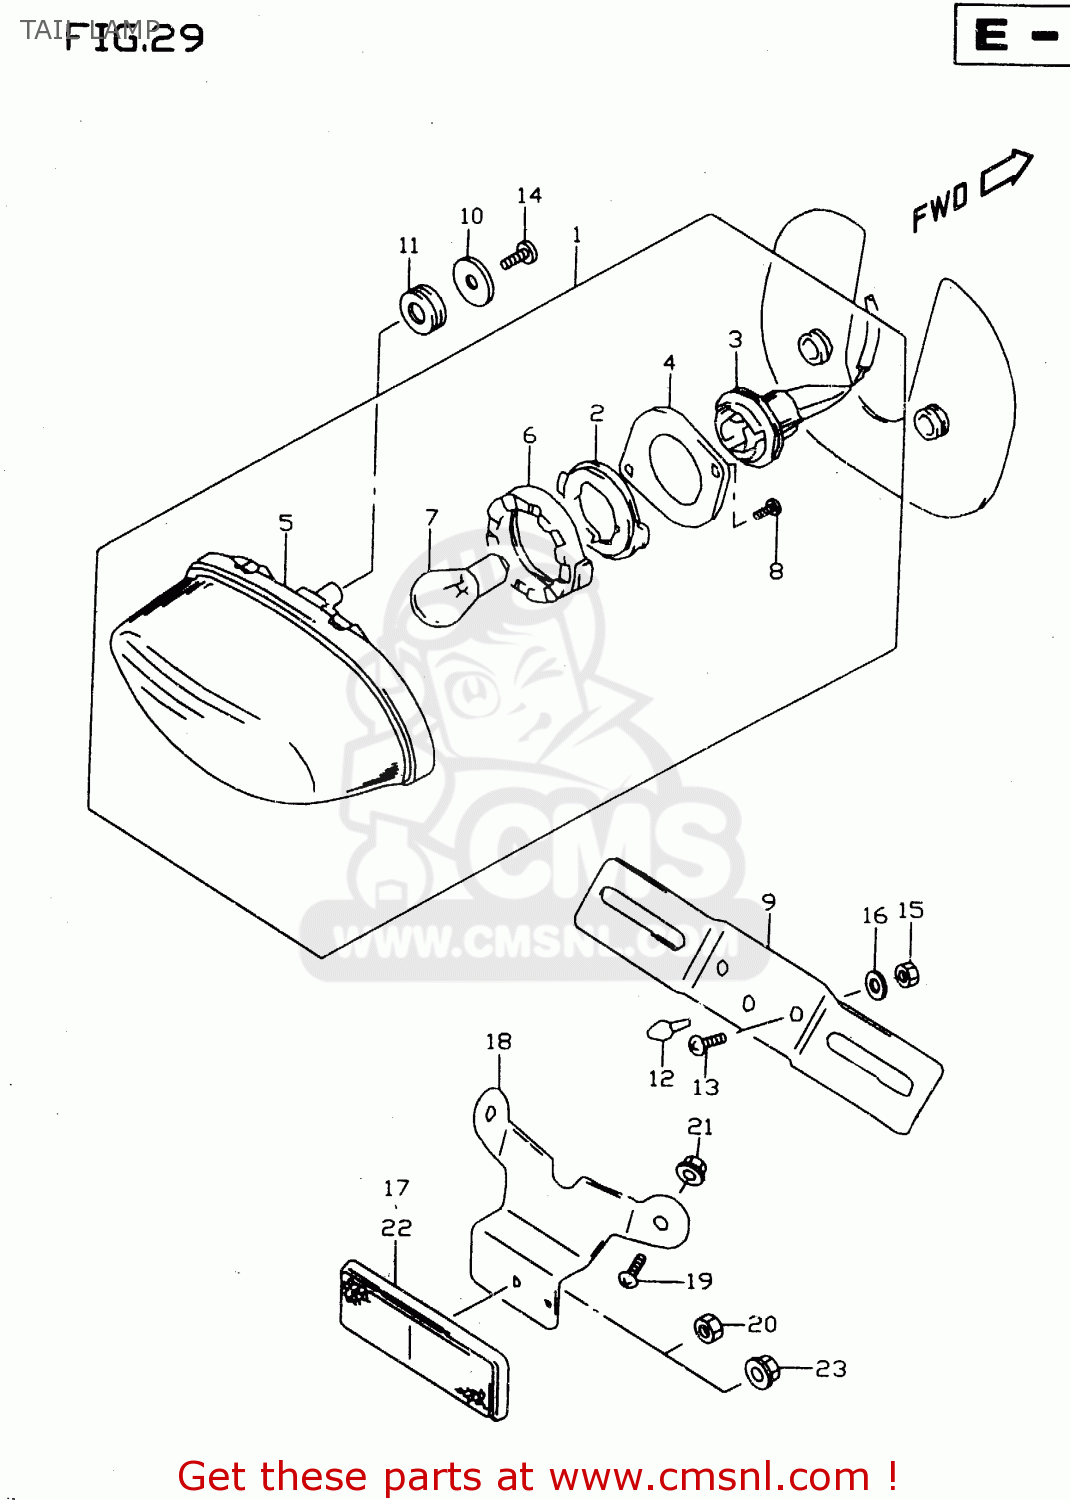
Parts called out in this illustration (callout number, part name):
1	LAMP,REAR COMB
2	PLATE NO.1
3	SOCKET & CORD
4	PLATE NO.2
5	LAMP UNIT
6	CUSHION
7	BULB(12V21/5W)
8	SCREW
9	PLATE,RR LICENSE
10	WASHER(5.5X20X1.2)
11	CUSHION
12	CUSHION
13	SCREW 6X12
14	SCREW
15	NUT 6MM
16	WASHER(6.5X20X1.2)
17	REFLECTOR ASSY,RR
18	BRACKET,RR REFLECTOR
19	SCREW(6X16)
20	NUT
21	NUT
22	REFLECTOR ASSY,RR
23	NUT
